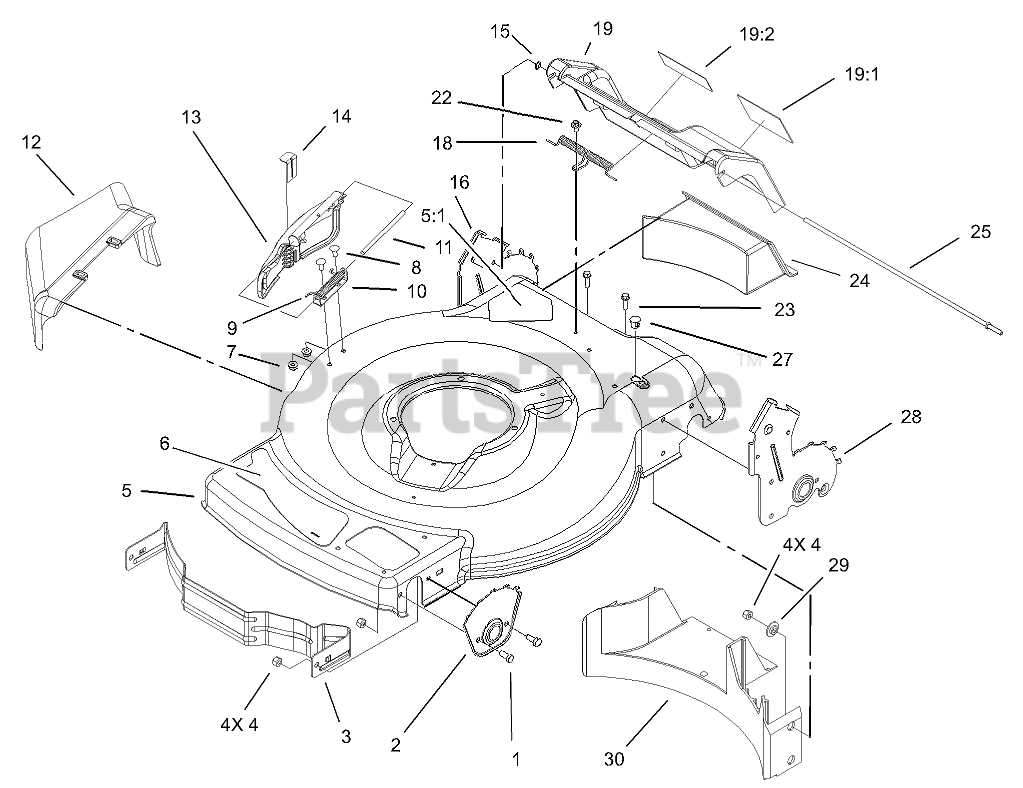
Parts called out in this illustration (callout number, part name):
1	SCREW-HH
2	Plate-HOC, Front
3	Baffle-Front
4	NUT-LOCK, NI
5	Housing (only on: 20016, 20019)
5	Housing (only on: 20012)
5:1	Decal-Danger, Cut Finger (only on: 20012)
5:1	Decal-Danger (only on: 20016, 20019)
6	Decal-Deck
7	NUT-HHF
8	SCREW-CARR
9	SPRING-TORSION
10	BRACKET-COVER
11	ROD-COVER
12	CHUTE-DISCHARGE, SIDE
13	Door-Discharge, Side
14	Lever-Latch
15	NUT-PUSH
16	RH Rear HOC Plate ASM (only on: 20012, 20016)
16	RH Rear HOC Plate ASM (only on: 20019)
18	Spring-Door, Rear
19	Door (only on: 20016, 20019)
19	Door (only on: 20012)
19:1	Decal-Warning (only on: 20012)
19:2	Decal Warning (only on: 20012)
19:2	Decal-Warning, Door (only on: 20016, 20019)
22	SCREW AND WASHER ASM
23	SCREW-HWH
24	Plug-Discharge, Rear
25	Rod-Pivot, Rear Door
27	Plug-Dome
28	LH Rear HOC Plate ASM (only on: 20012, 20016)
28	LH Rear HOC Plate ASM (only on: 20019)
29	Washer-Stepped
30	Baffle-Rear
